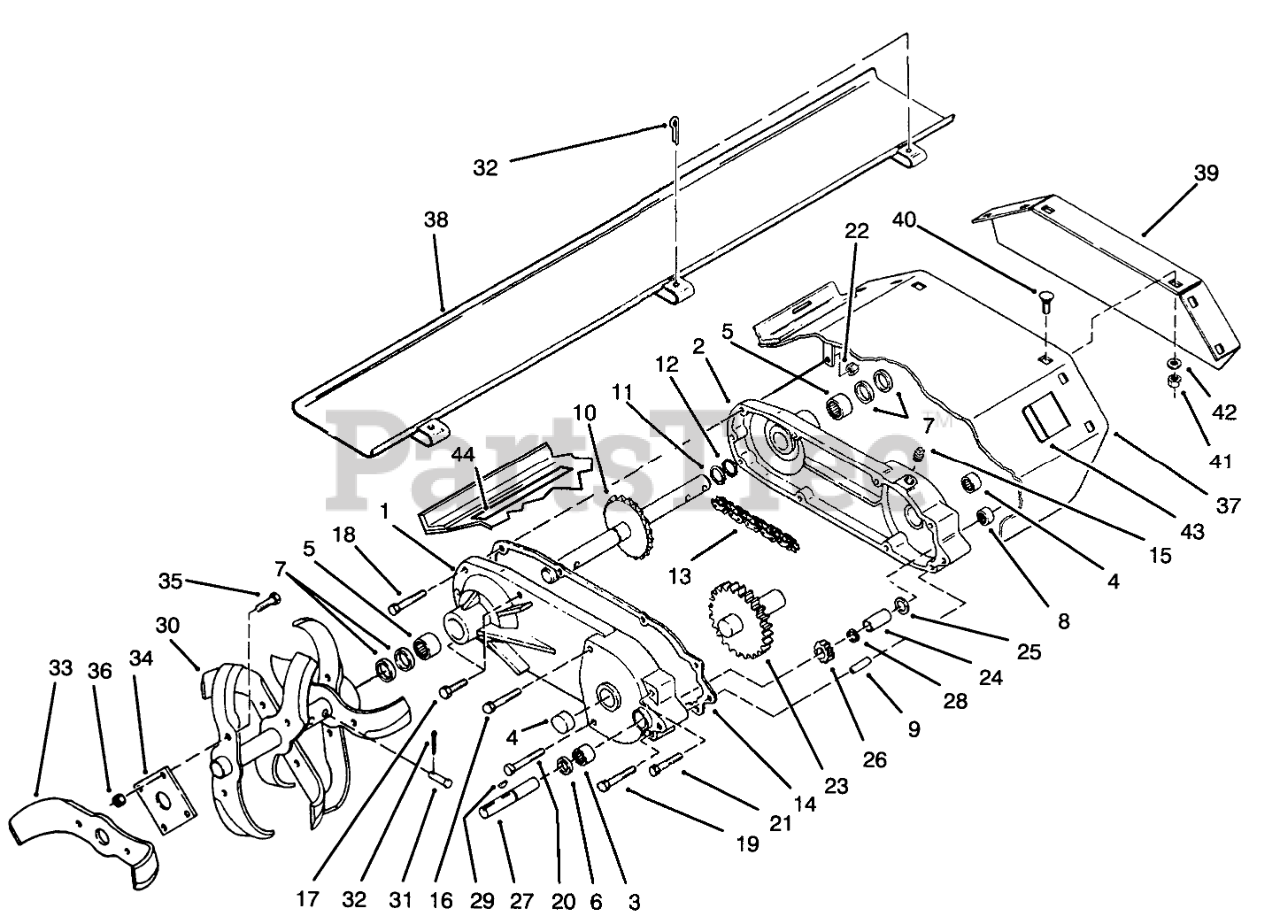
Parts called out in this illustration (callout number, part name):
1	GEAR CASE TILLER RED
2	GEAR CASE TILLER RED
3	BEARING-NEEDLE
4	BEARING-NEEDLE
5	BEARING-NEEDLE
6	SEAL-OIL
8	BEARING-NEEDLE
9	PIN-ROLL
10	TINE SHAFT ASM
11	RING-RETAINING
12	WASHER
13	CHAIN
14	GASKET-TRANSMISSION
15	PLUG-PIPE, SQH
16	SCREW-HH
17	SCREW-HH
18	SCREW-HH
19	SCREW-HH
20	SCREW-HH
21	SCREW-HH
22	NUT-LOCK, NI
23	GEAR AND SHAFT ASM
24	TUBE-SPACER
25	WASHER-THRUST
26	GEAR-PINION
27	SHAFT-INPUT
28	Ring-Snap
29	KEY-WOODRUFF
30	RH TINE ASM
31	PIN-CLEVIS
32	PIN-COTTER
33	TINE-RH
34	PLATE-TINE MOUNTING
35	SCREW-HH
36	NUT-LOCK, NI
37	Shield-Tine (Incl. ref.#43)
38	GUARD ASM
39	COVER-TINE END
40	BOLT-CARR
41	NUT-LOCK, NI
42	WASHER-PLAIN
43	DECAL-DANGER
44	DECAL-ATTACHMENT
